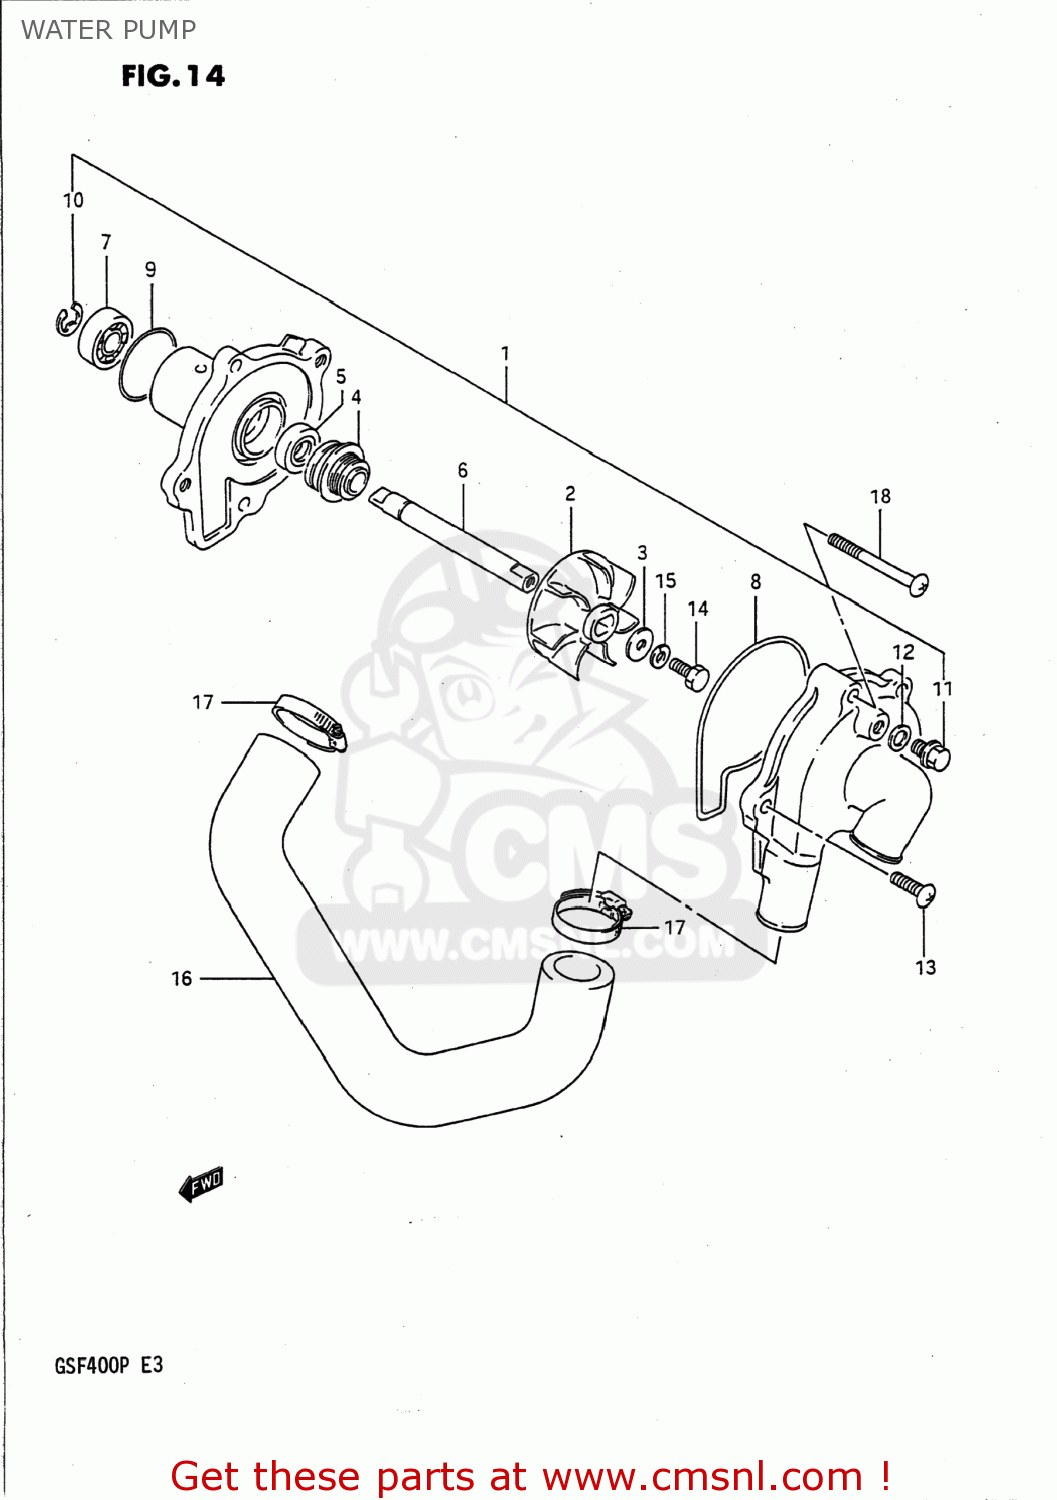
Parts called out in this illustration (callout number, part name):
1	PUMP ASSEMBLY,WATER
2	IMPELLER,WATER PUMP
3	GASKET(6X15X2.2) (NAS)
4	SEAL,MECHANICAL
5	OILSEAL
6	SHAFT,WATER PUMP
7	BEARING,10X26X8
8	O RING
9	O RING,WATER PUMP HOLDER
10	E RING
11	BOLT,DRAIN
12	GASKET 8.2X14X1 (NAS)
13	SCREW
14	BOLT(6X13)
15	WASHER
16	HOSE,WATER PUMP OUTLET
17	CLAMP
18	SCREW
